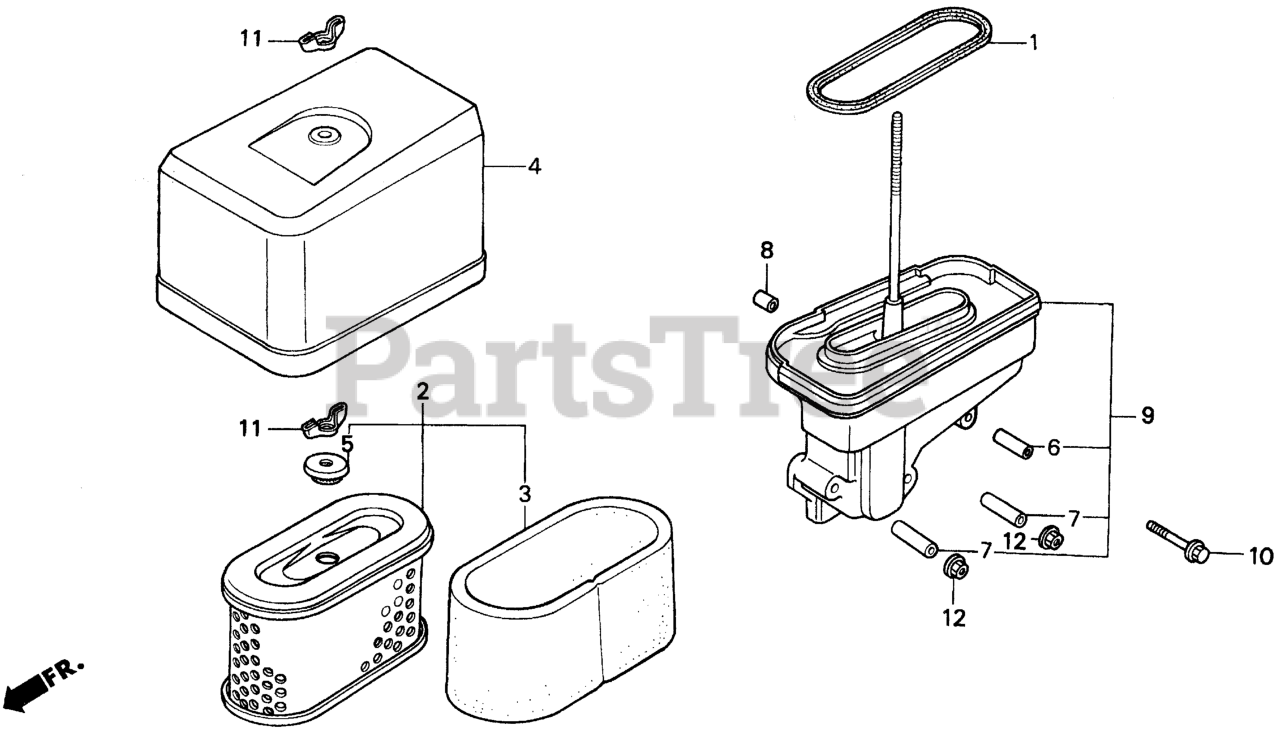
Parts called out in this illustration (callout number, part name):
1	GASKET, ELBOW
2	ELEMENT, AIR CLEANER (METAL BASE)
3	FILTER,OUTER
3	FILTER (OUTER)
4	COVER, AIR CLEANER (DUAL)
5	GROMMET, AIR CLEANER
6	COLLAR, AIR CLEANER Use up to Engine SN 1786084.
7	COLLAR, AIR CLEANER
8	SPACER, AIR CLEANER ELBOW
9	ELBOW, AIR CLEANER
10	BOLT, FLANGE (6X57)
11	WINGNUT, TOOL BOX SETTING
12	NUT, FLANGE (6MM)
